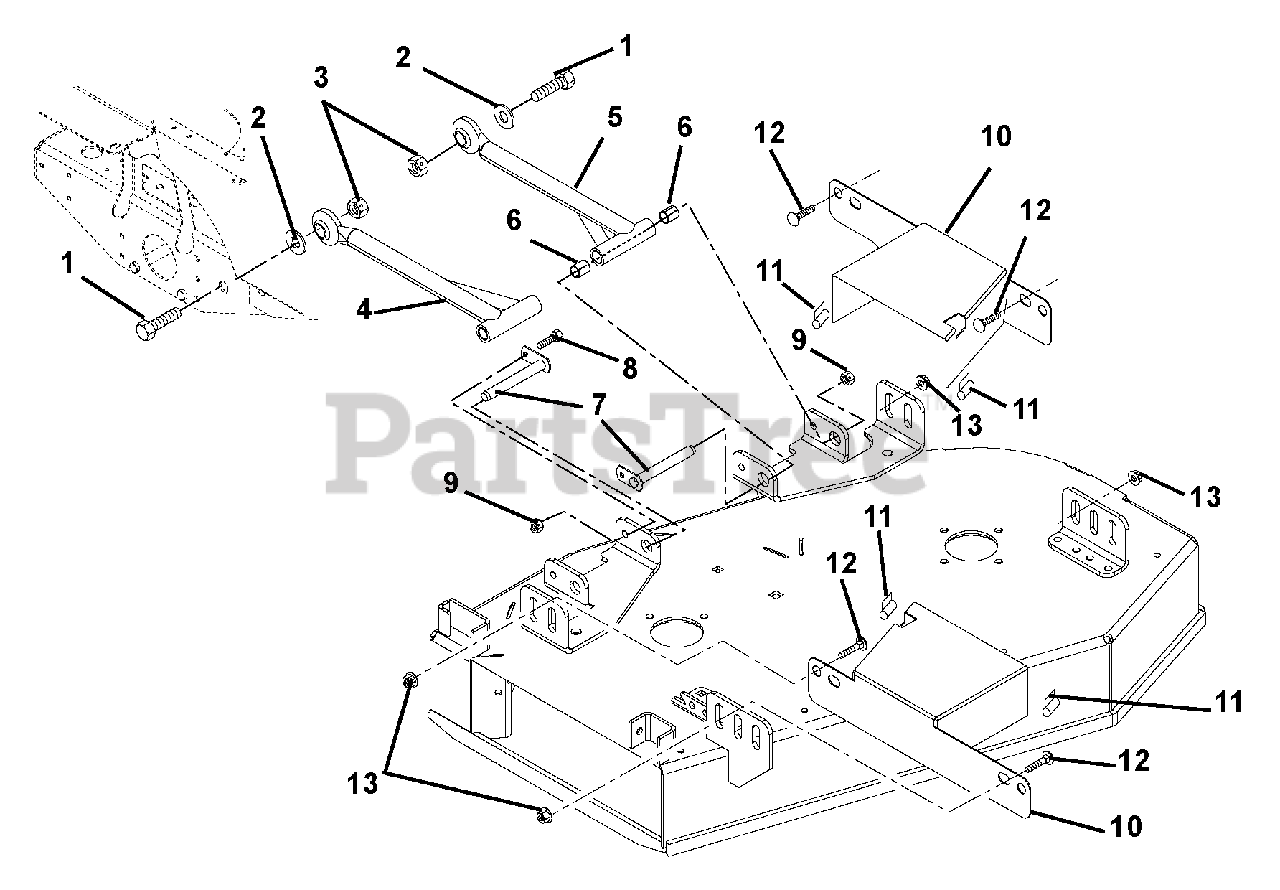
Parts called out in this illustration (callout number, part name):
1	Bolt, Hex .875-9 x 3.00
2	Bushing, Sleeve .875 x 1.25 x .531
3	Nut, Locking Center .875-9
4	Assembly, Mower Mounting
5	Arm, Mower Mounting
6	Bearing, .75 x .875 x 1.00
7	Weldment, Mower Mounting Pin
8	Bolt, Hex .38-16 x .88
9	Nut, Nyloc Flange 3/8-16
10	Guard, 34" Belt
11	Seal, Trim-LOK Bulk .06 Bubble
12	Bolt, Round Head Square Neck .50-13 x 1.00 Grade 5
13	Nut, Nyloc Flange .50-13
